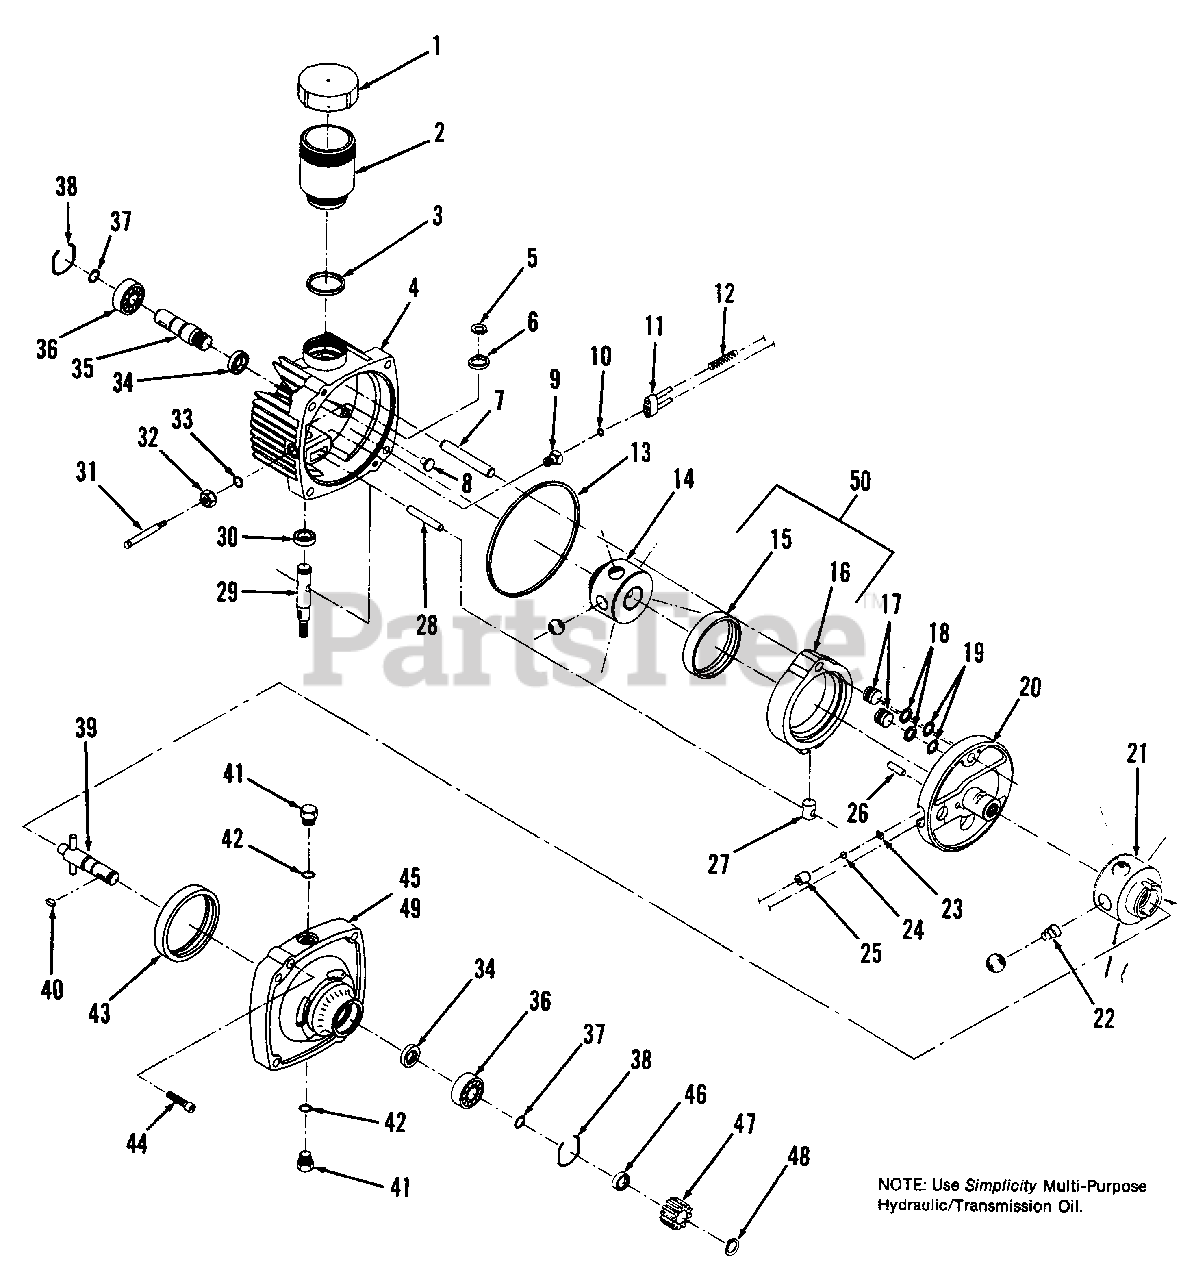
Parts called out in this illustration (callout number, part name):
1	RESERVOIR COVER, Sub-Assy.
2	RESERVOIR BODY
3	SEAL RING, Square Cut
4	COVER, Service Kit (Includes Ref. Nos. 5, 6, 7, 28, 29, 30 & 34)
5	RING, External Retaining
6	WASHER, Control Shaft
9	FITTING GUIDE, O-Ring S.A.
10	O-RING
11	BRACKET, Pins, Sub-Assy.
12	SPRING, Valve
13	SEAL RING, Square Cut
14	PUMP ROTOR, Ball, Sub-Assy.
19	O-RING
20	PINTLE, Sub-Assy. (Includes Ref. Nos. 17, 18, 19, 23, 24, 25 & 26)
21	MOTOR ROTOR, Ball, Sub-Assy. (Includes Qty. 5 of Ref. No. 22)
22	SPRING, Piston
27	CAM RING, Insert
30	SEAL, Oil
31	SHAFT, Dump Valve
32	NUT, Gasket, Sub-Assy.
33	O-RING
34	SEAL, Oil
35	SHAFT, Input
36	BEARING, Ball (Input)
38	RING, Retaining
39	OUTPUT SHAFT, Sub-Assy.
40	KEY, Woodruff
41	O-RING, Plug, Sub-Assy.
42	TUBE FITTING, O-Ring
44	CAPSCREW, Socket Hd.
48	RING, External Retaining
49	BODY, Sub-Assy. (Includes Ref. Nos. 34, 36, 37, 38, 39, 43 & 45)
50	CAM RING, Sub-Assy. (Includes Ref. Nos. 15 & 16)
